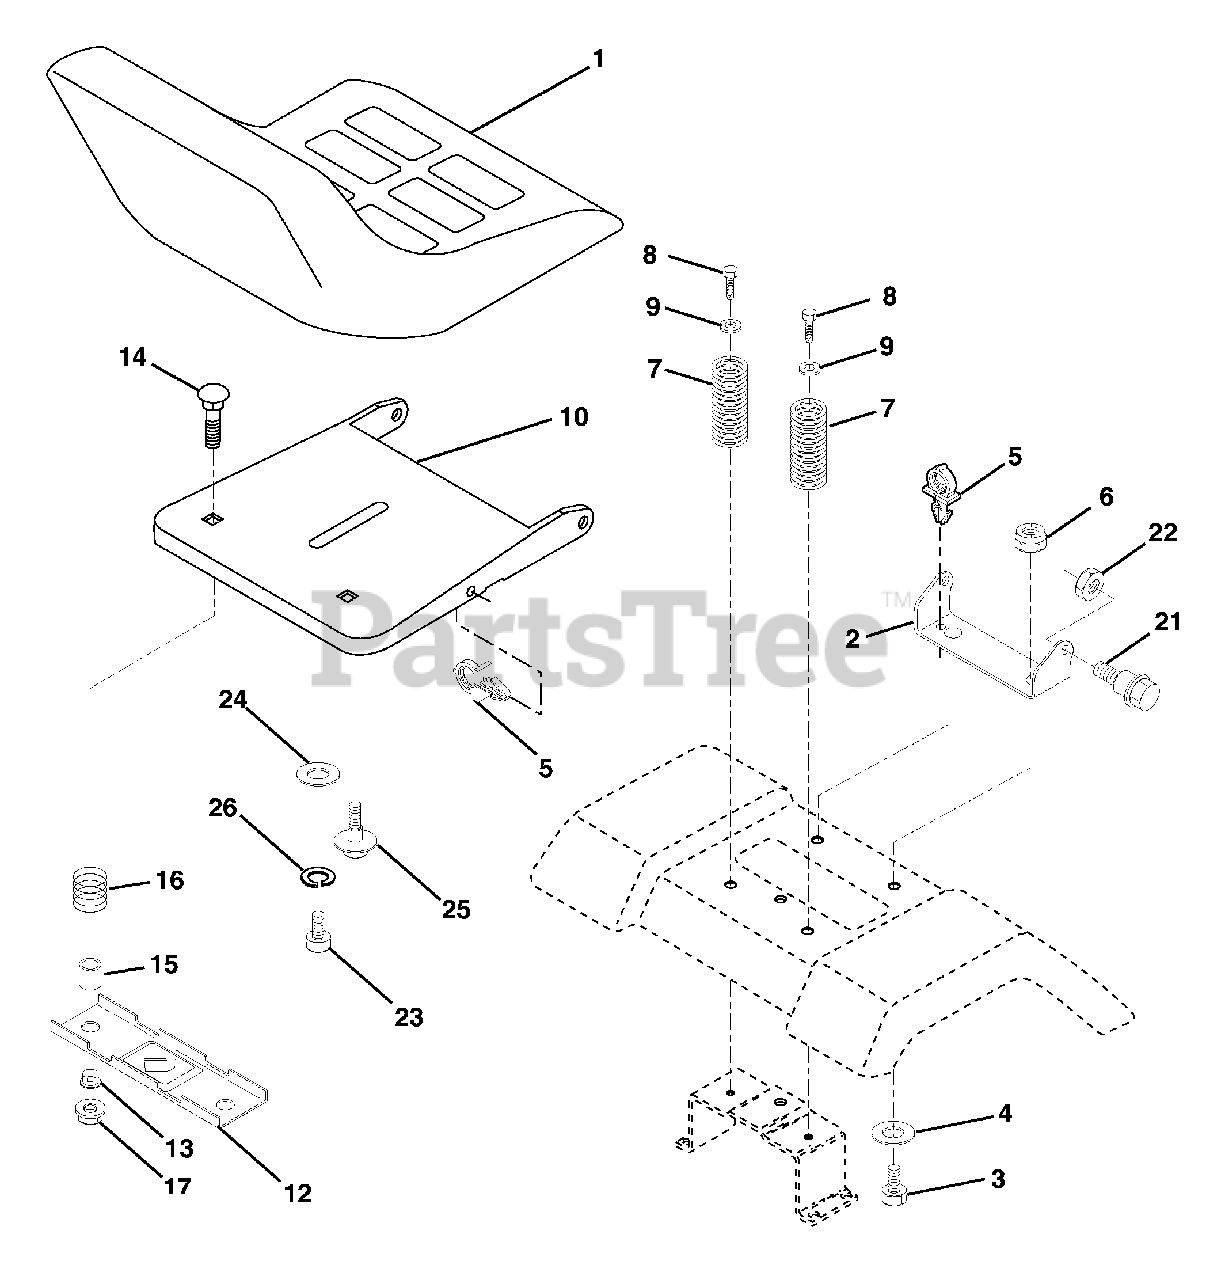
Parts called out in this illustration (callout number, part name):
1	Seat
2	Bracket Seat Pivot
3	Bolt Hex 3/8 - 16 x 1
4	Washer 13/32 x 1 x10 Ga.
5	Clip Push-In Hinged
6	Nut Lock Hex w/Ins 3/8 - 16
7	Spring Seat Cprsn 2 250 Blk Zi
8	Screw 3/8-16 x 1.5
9	Washer 13/32 x 1 x 14 Ga.
10	Pan Pnt Seat (Blk)
12	Bracket Pnt Mounting Switch
13	Bushing Snap Blk Nyl
14	Bolt Rdhd Sht Nk 1/4 - 20 x 1 -1/2
15	Spacer Split .28 x .96
16	Spring Cprsn
17	Nut Lock 1/4 Lge Flg
21	Bolt Shoulder 5/16-18 unc-2A
22	Nut Lock Hex w/Ins 5/16 - 18
23	Bolt Hex
24	Washer 17/32 x 1-3/16 x 12 Ga.
25	Bolt Shoulder 5/16-18 x .62
26	Washer Lock Hvy Hlcl Spr 1/2
